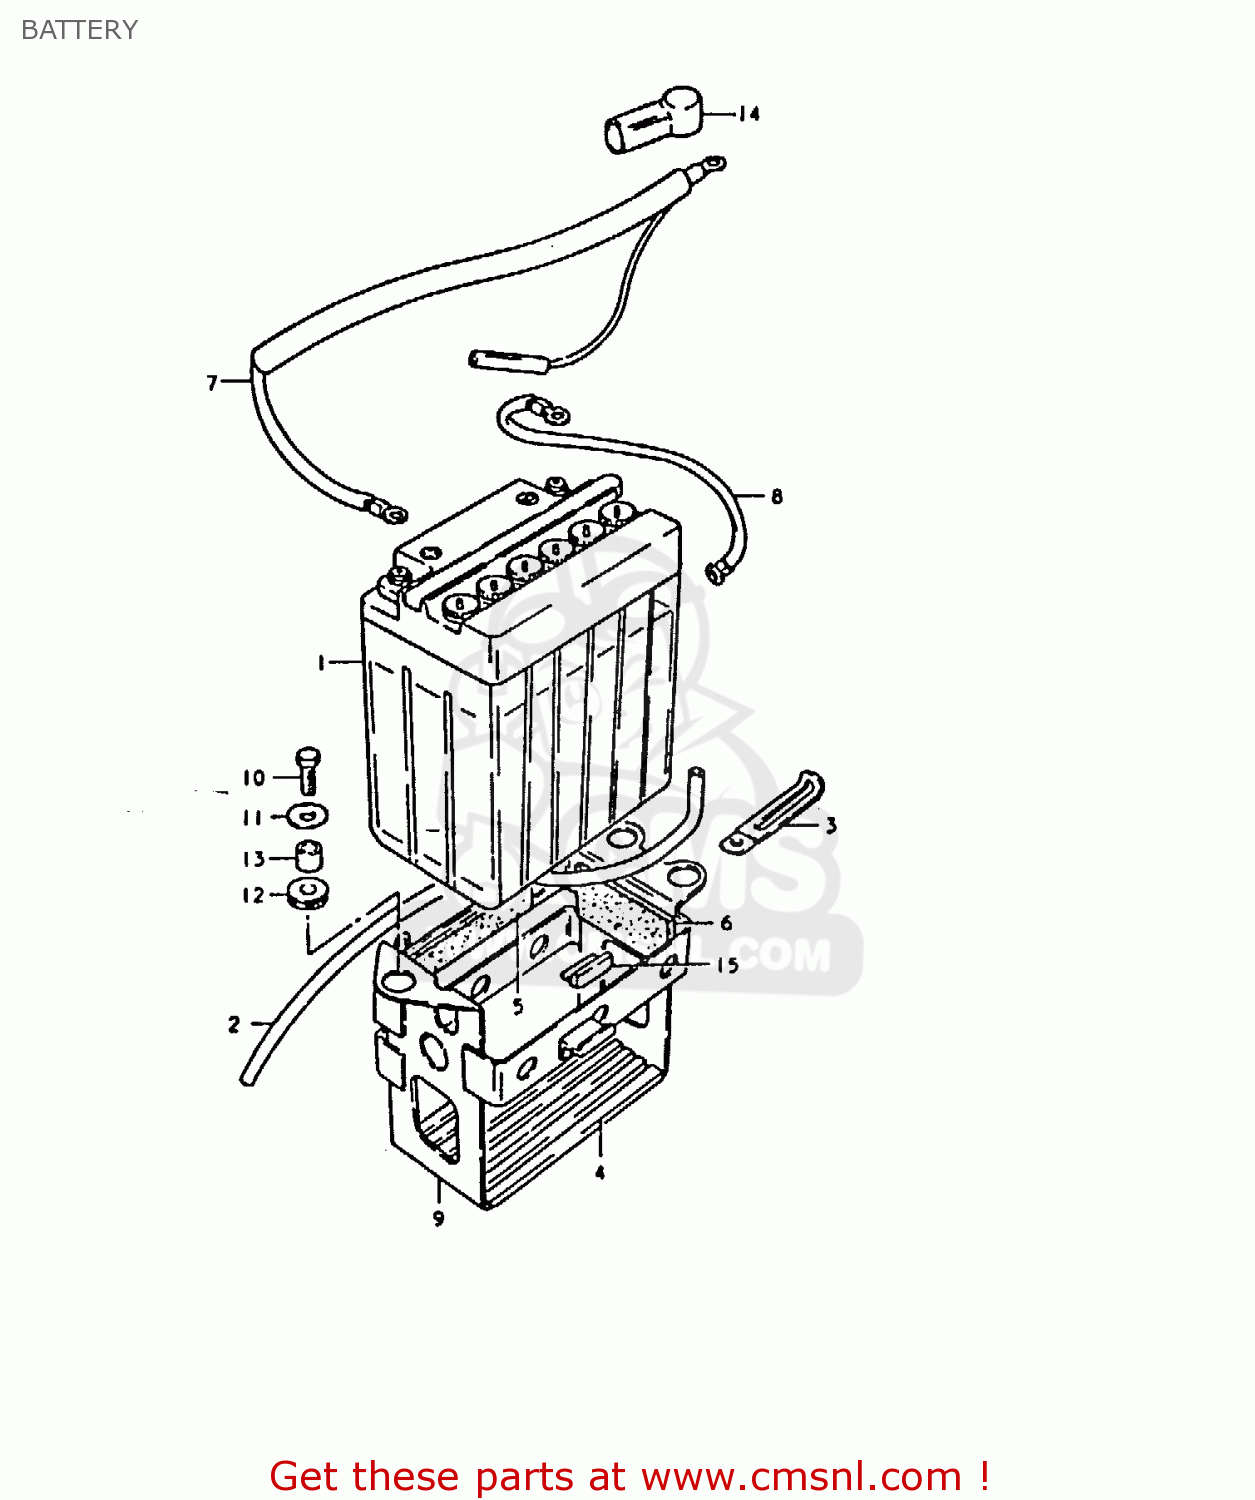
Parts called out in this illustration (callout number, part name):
1	BATTERY ASSY (12V)
2	HOSE,BATTERY EXHAUST
3	CLAMP L:35
4	PROTECTOR,BATTERY
5	PROTECTOR(20X90)X4
6	PROTECTOR,BATTERY
7	WIRE,BATTERY PLUS
8	LEAD WIRE,BATTERY(-)
9	HOLDER,BATTERY
10	BOLT, UPPER
11	WASHER
12	CUSHION
13	SPACER(6.1X9X7.5)
14	CAP,TERMINAL
15	CUSHION,FRAME COVER
